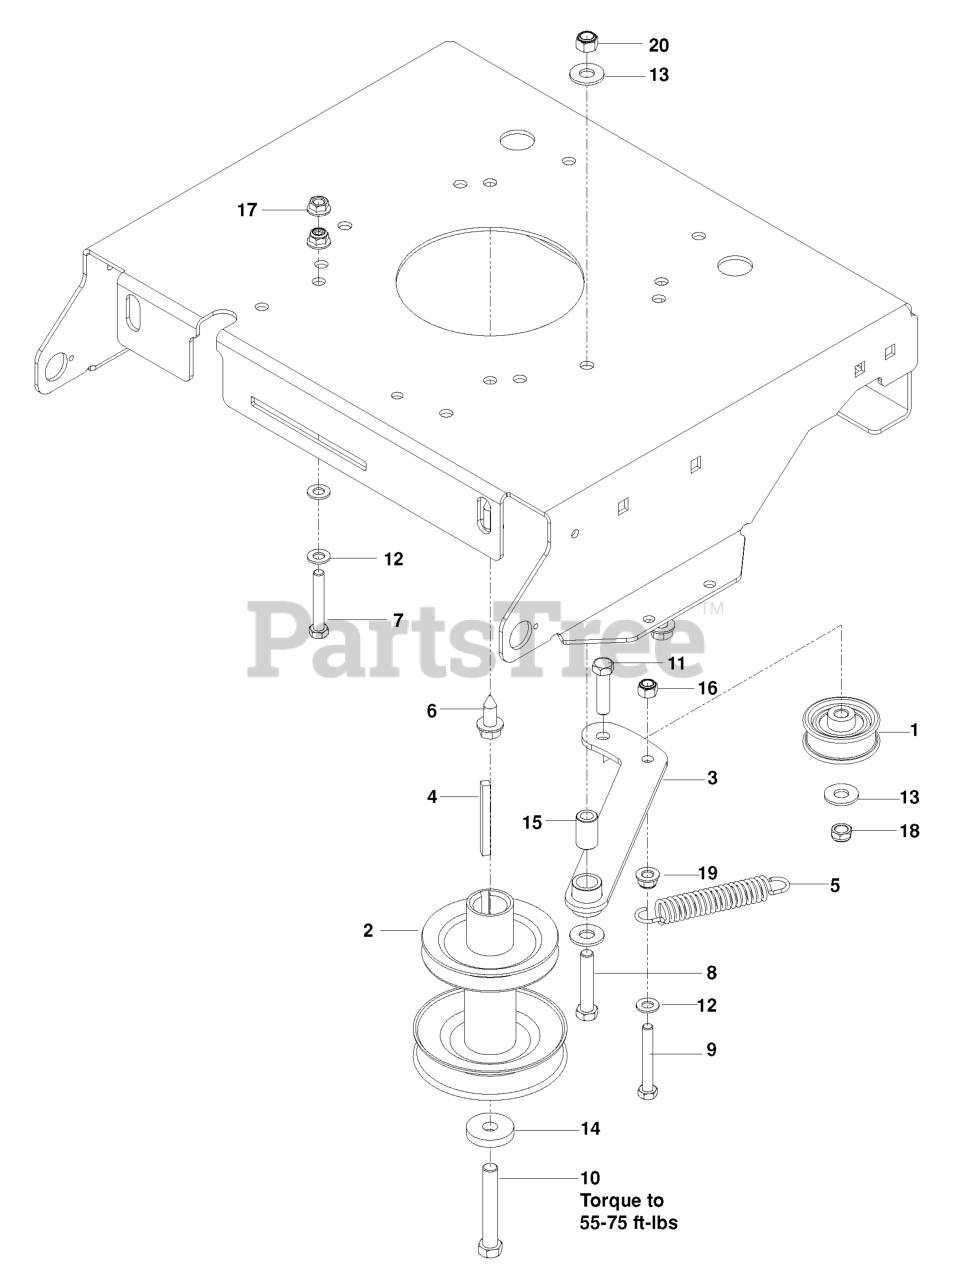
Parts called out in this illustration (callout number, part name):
1	PULLEY IDLER
2	PULLEY, ENGINE 30"
3	IDLER WLDT.
4	KEY 1/4 SQ X 2-1/2
5	SPRING - 3.50
6	HHFS 3/8-16 X 1.0 THD FORMING
7	HCS 5/16-18X2
8	HCS 3/8C X 2
10	HCS 7/16-20 X 2-3/4
11	HCS 3/8C X 1 1/2
12	FLAT WASHER 5/16 SAE
13	WASHER 3/8 FLAT
14	WASHER .43X1.38X.25
16	NUT 5/16 NYLOC
17	NUT 5/16C WHIZ
18	NUT HEX 3/8-16 NYLON, THIN
19	5/16-18 NYLOC FLANGE NUT
20	NUT 3/8-16 NYLOC
